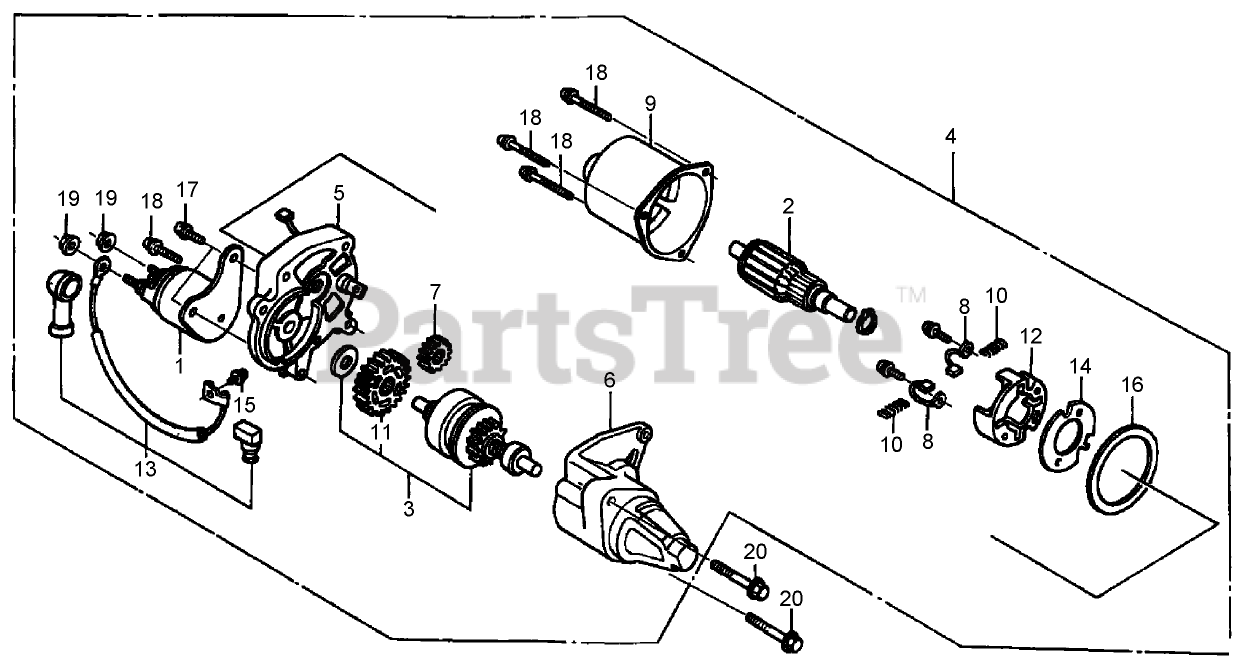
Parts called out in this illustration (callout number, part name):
1	CONTACTOR ASM
2	ARMATURE
3	CLUTCH-OVERRUNNING
4	MOTOR UNIT-STARTER
5	BRACKET-CENTER
6	BRACKET-FR
7	GEAR-DRIVE PINION
8	BRUSH
9	YOKE
10	SPRING-BRUSH RETURN
11	GEAR-REDUCTION
12	HOLDER-BRUSH
13	WIRE-WATER COVER
14	INSULATOR
15	SCREW-WASHER (4X6)
16	GASKET
17	BOLT-WASHER (5X14)
18	SCREW-WASHER (5X3)
19	NUT-WASHER (6MM)
20	BOLT-FLANGE (8X35)
